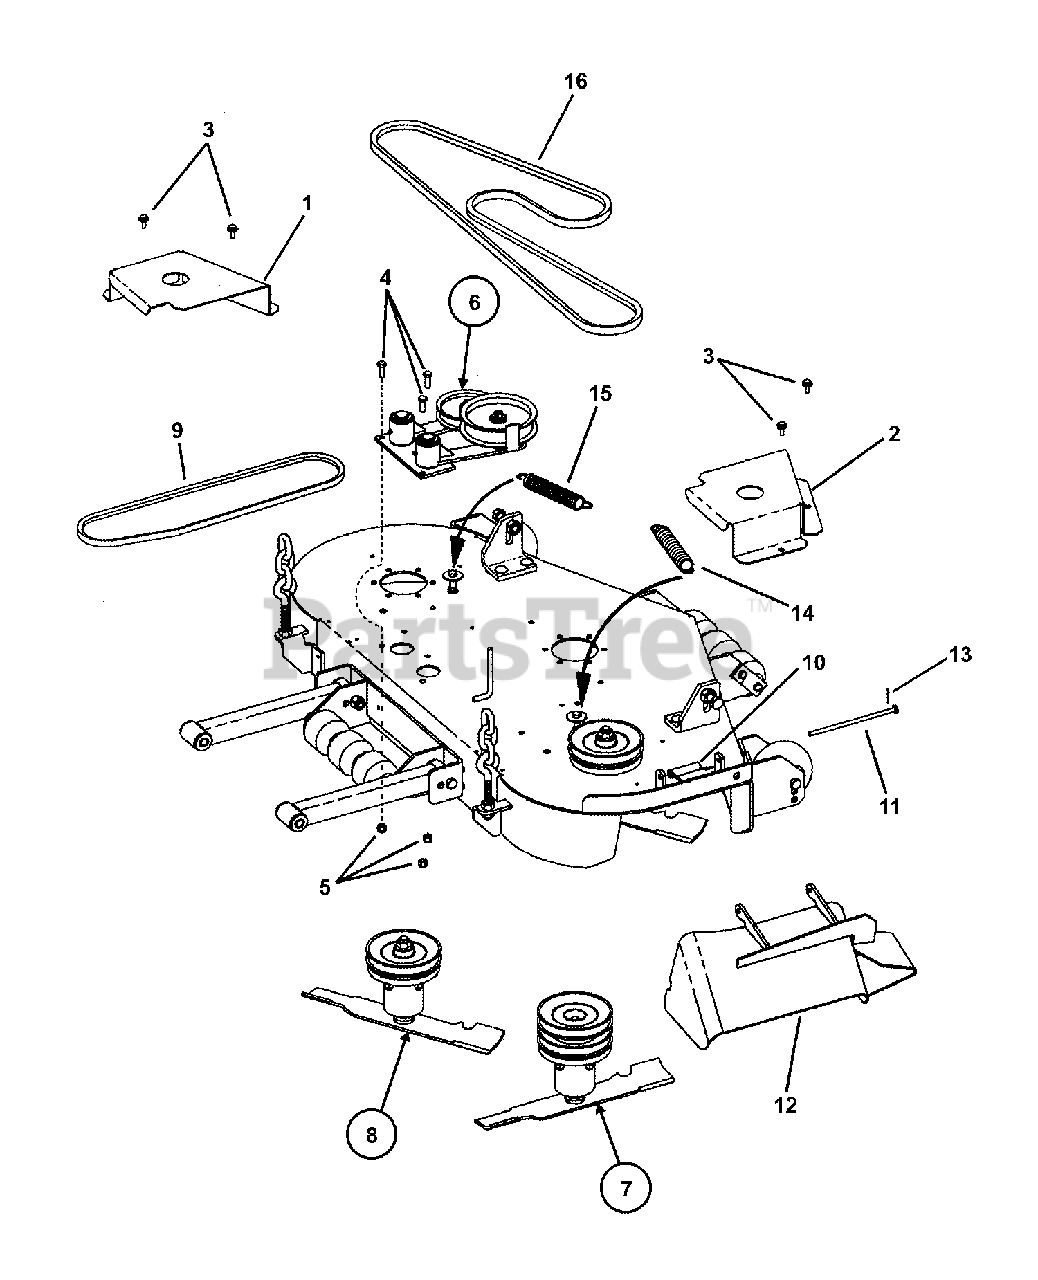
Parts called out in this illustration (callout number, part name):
1	BELT COVER, Left Hand
2	BELT COVER, Right Hand
3	SCREW, 5/16-18 x 5/8" Hex Washer Self-Tap
4	BOLT, 3/8-16 X 1" GD5 CZ
5	NUT, 3/8-16 HEX NYLON LOCK
6	ASSEMBLY, Idler
7	ASSEMBLY, Center Spindle
8	ASSEMBLY, Spindle
9	BELT, Primary (HB Section, 91.30" effective length)
10	SPRING, Chute
11	PIN, Chute Hinge
12	WELDMENT, Chute Deflector (52" Euro)
13	PIN, 3/32 x 1" Cotter
14	SPRING, Idler Primary (1.25" O.D. x 10" long)
15	SPRING, Idler (1.17" O.D. x 7.5" long)
16	V-BELT, Secondary- 52" (HB Section, 116.30" effective length)
